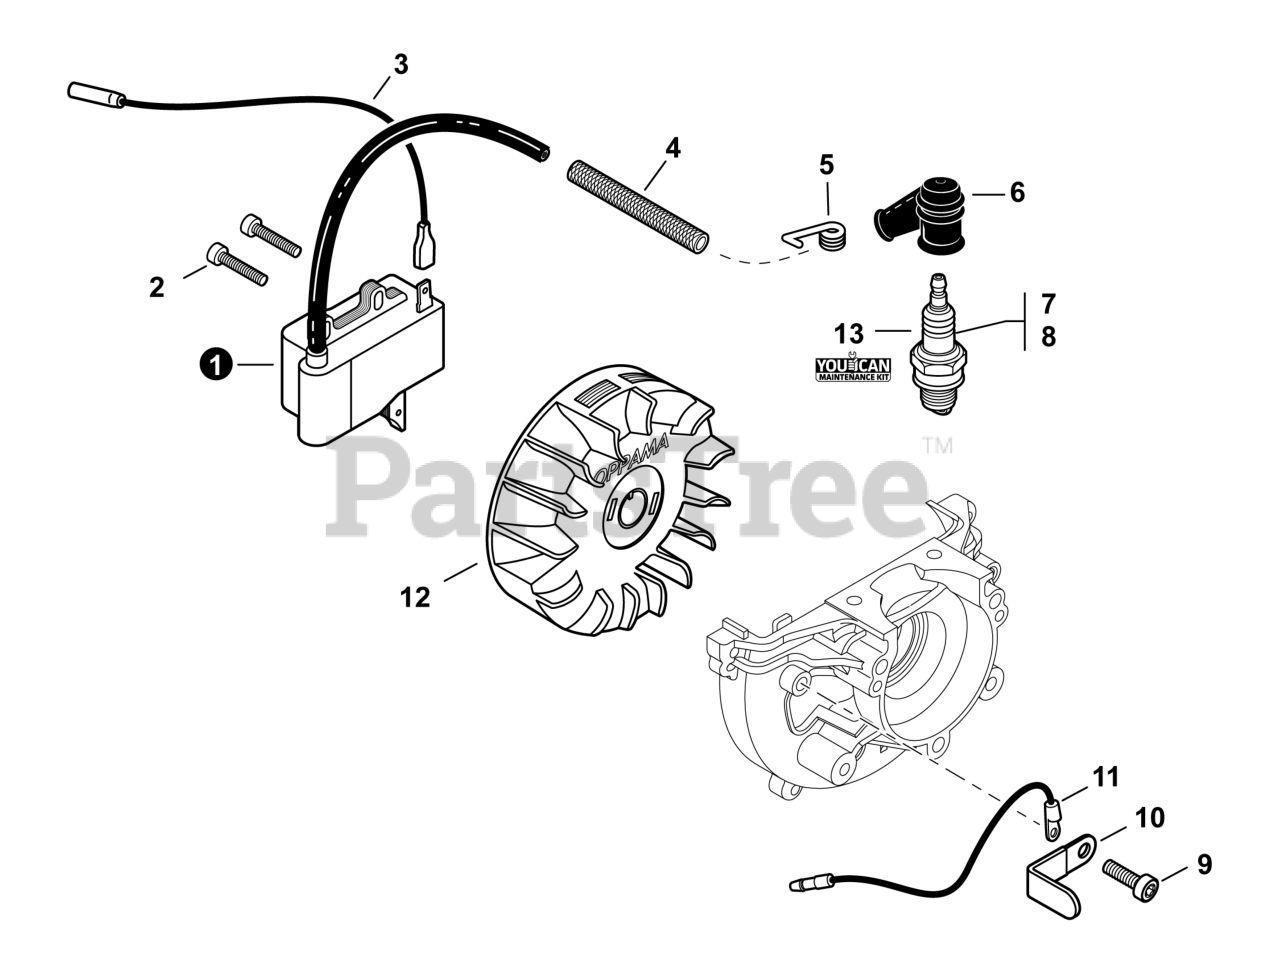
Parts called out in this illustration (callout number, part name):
1	COIL, IGNITION
2	BOLT, TORX 4x20
3	LEAD - IGNITION L= 210
4	TUBE, INSULATOR 8 L= 65
5	TERMINAL, SPARK PLUG
6	CAP, SPARK PLUG
7	SPARK PLUG - BPM8Y
8	SPARK PLUG - BPMR8Y
9	BOLT, TORX 5x10
11	LEAD - GROUND L= 115
12	FLYWHEEL
13	TUNE-UP KIT - YOUCANT
